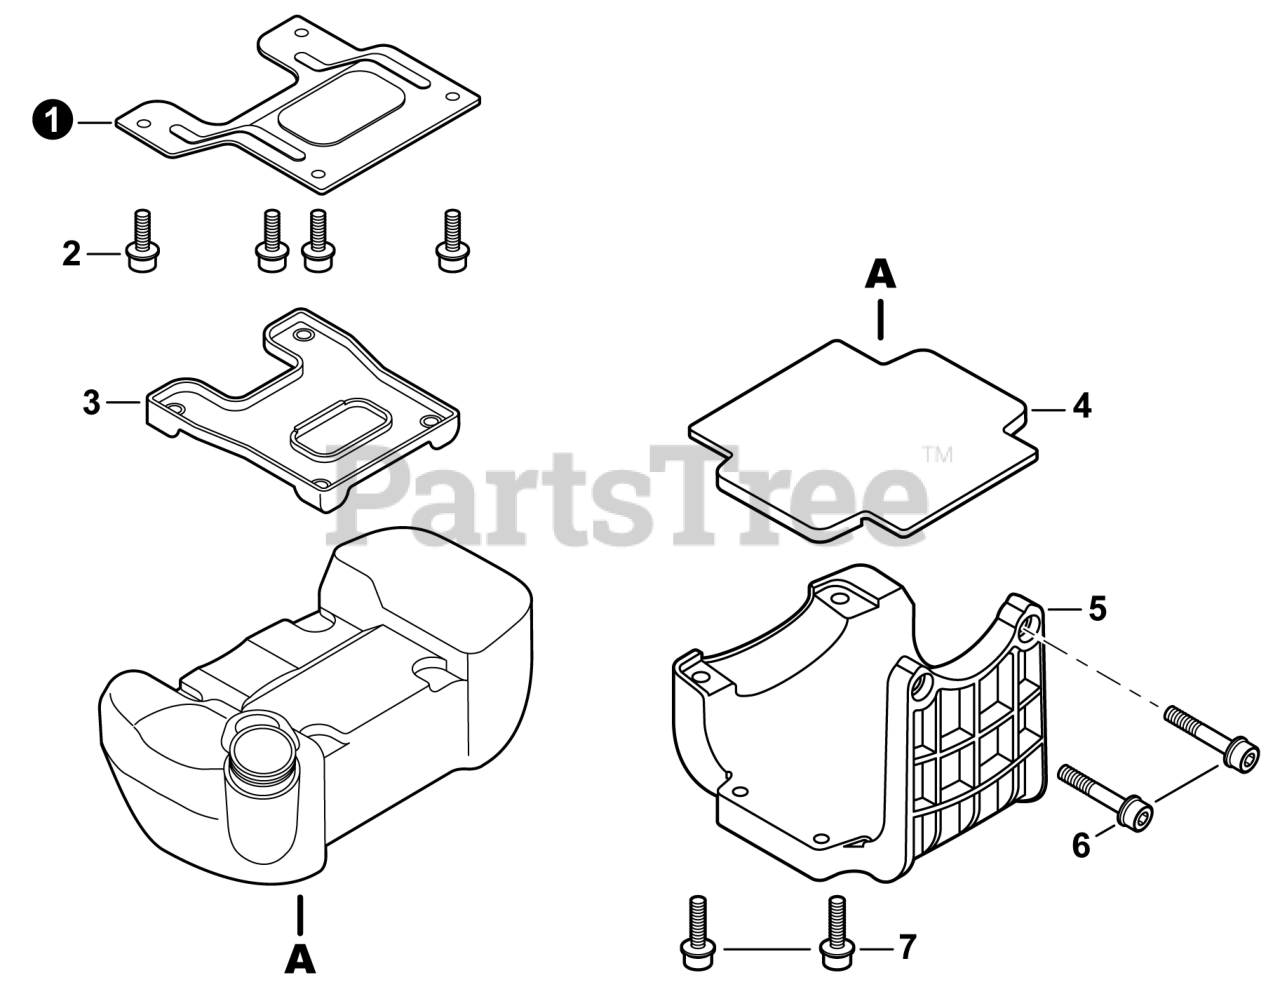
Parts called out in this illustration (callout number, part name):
1	BRACKET, FUEL TANK
2	BOLT 5x12
3	CUSHION, UPPER
4	CUSHION, FUEL TANK
5	GUARD, FUEL TANK
6	BOLT 5x25
7	BOLT 5x20
